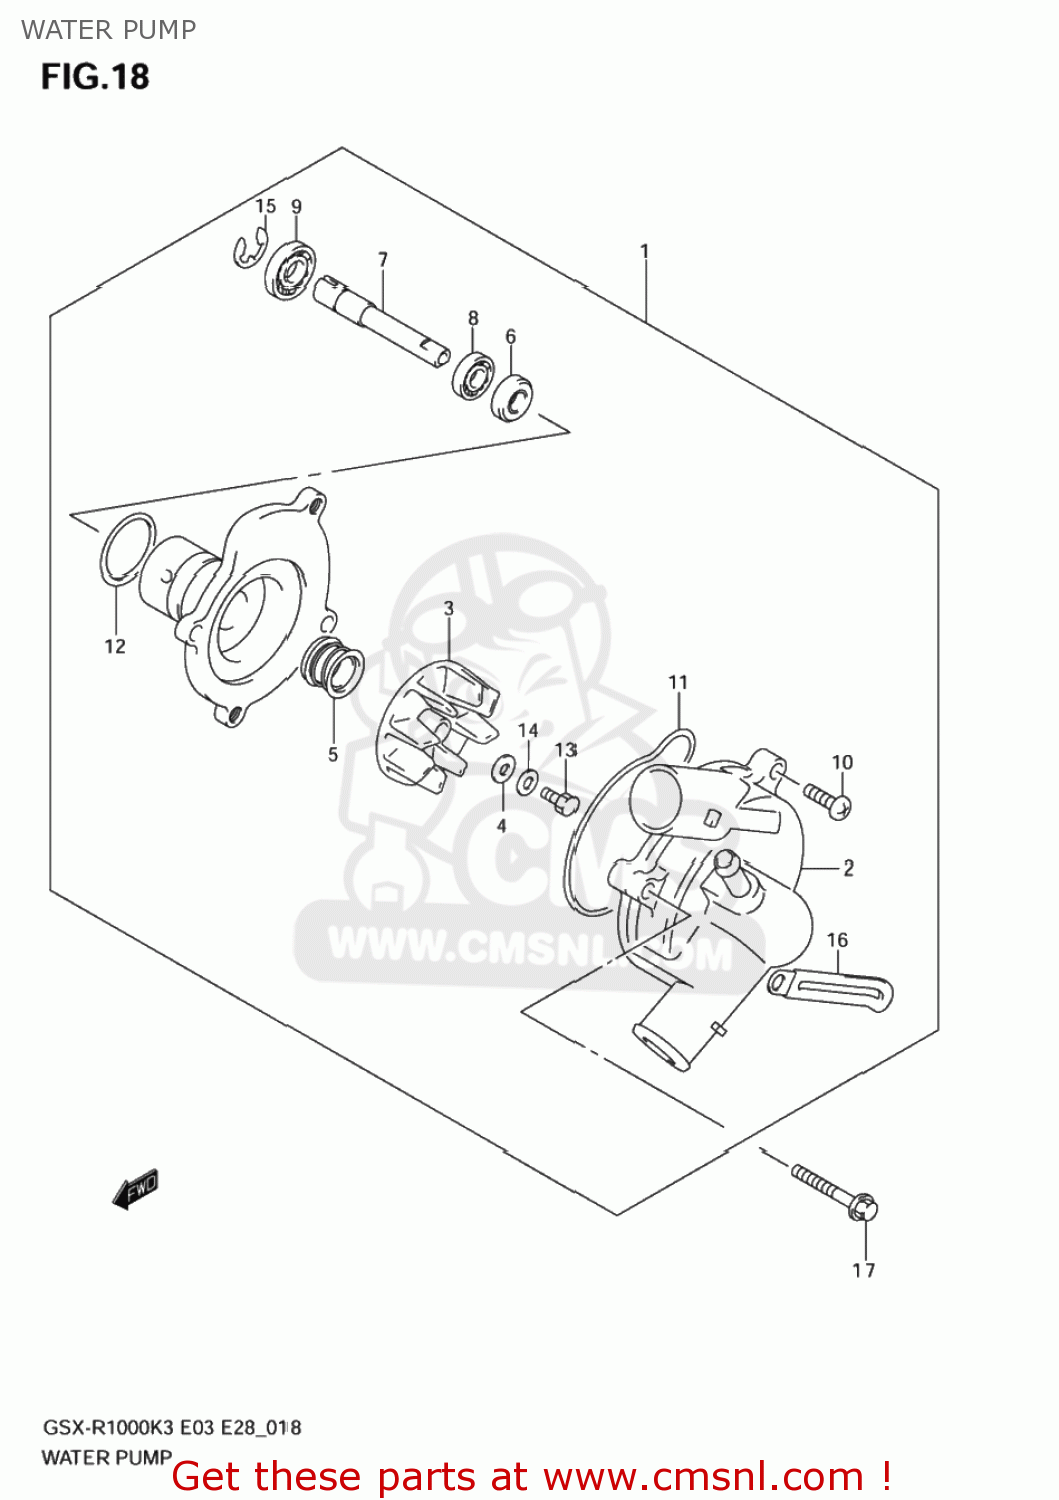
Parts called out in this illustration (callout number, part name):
1	PUMP ASSY,WATER
2	CASE,WATER PUMP
3	IMPELLER
4	GASKET(6X15X2.2) (NAS)
5	SEAL,MECHANICAL
6	SEAL,OIL
7	SHAFT
8	BEARING(10X26X8)
9	BEARING(12X28X8)
10	SCREW 6X16
11	O RING
12	O RING
13	BOLT(6X13)
14	WASHER
15	E RING
16	CLAMP(L:65)
17	BOLT
